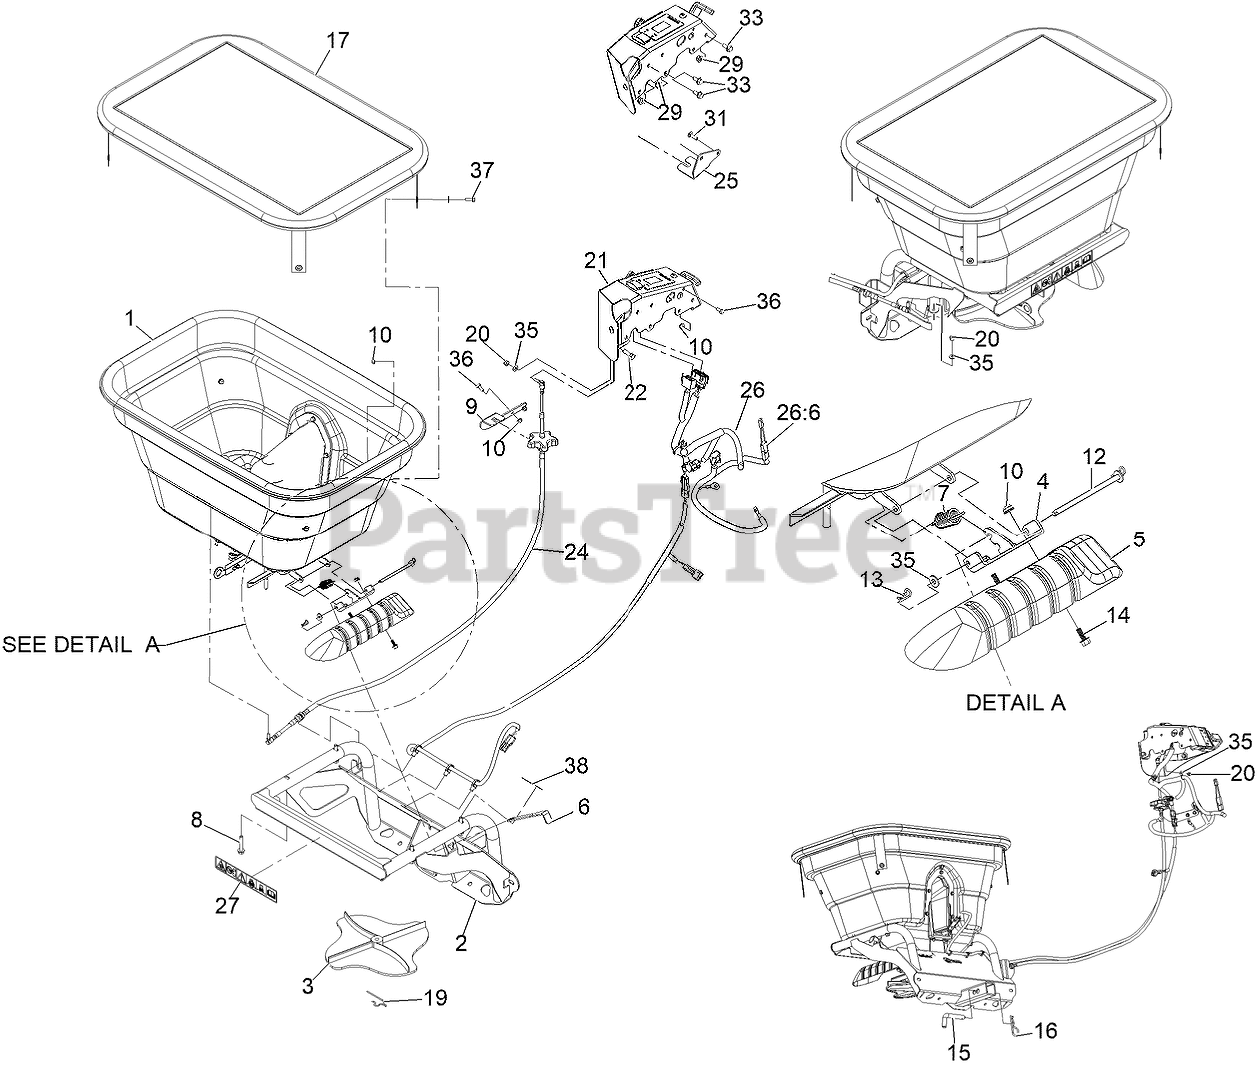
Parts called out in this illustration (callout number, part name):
1	ASY-SPREADER HOPPER (EXMARK)
2	SPREADER HOPPER FRAME ASM
3	Spinner-Spreader
4	BRACKET-DEFLECTOR
5	DEFLECTOR
6	STRAP-ENGAGEMENT
7	Spring-Extension
8	Screw-HWH
9	BRACKET-CABLE
12	PIN-PIVOT
13	PIN-COTTER
14	SCREW-HHF
15	PIN-HITCH
16	PIN-HAIR
17	COVER-HOPPER
19	Clip-Spinner
20	NUT-LOCK
21	SPREADER CONTROLLER ASM
22	SCREW-HH
24	CABLE-PUSH, PULL
25	BRACKET-CABLE
26	HARNESS
26:6	CONNECTOR
27	DECAL-DOWN, TIE
29	NUT-HF, NI
31	SCREW-CARR
33	SCREW-HHF
35	WASHER-FLAT
36	SCREW-HH
37	SCREW-HWH
38	DECAL-WARNING
